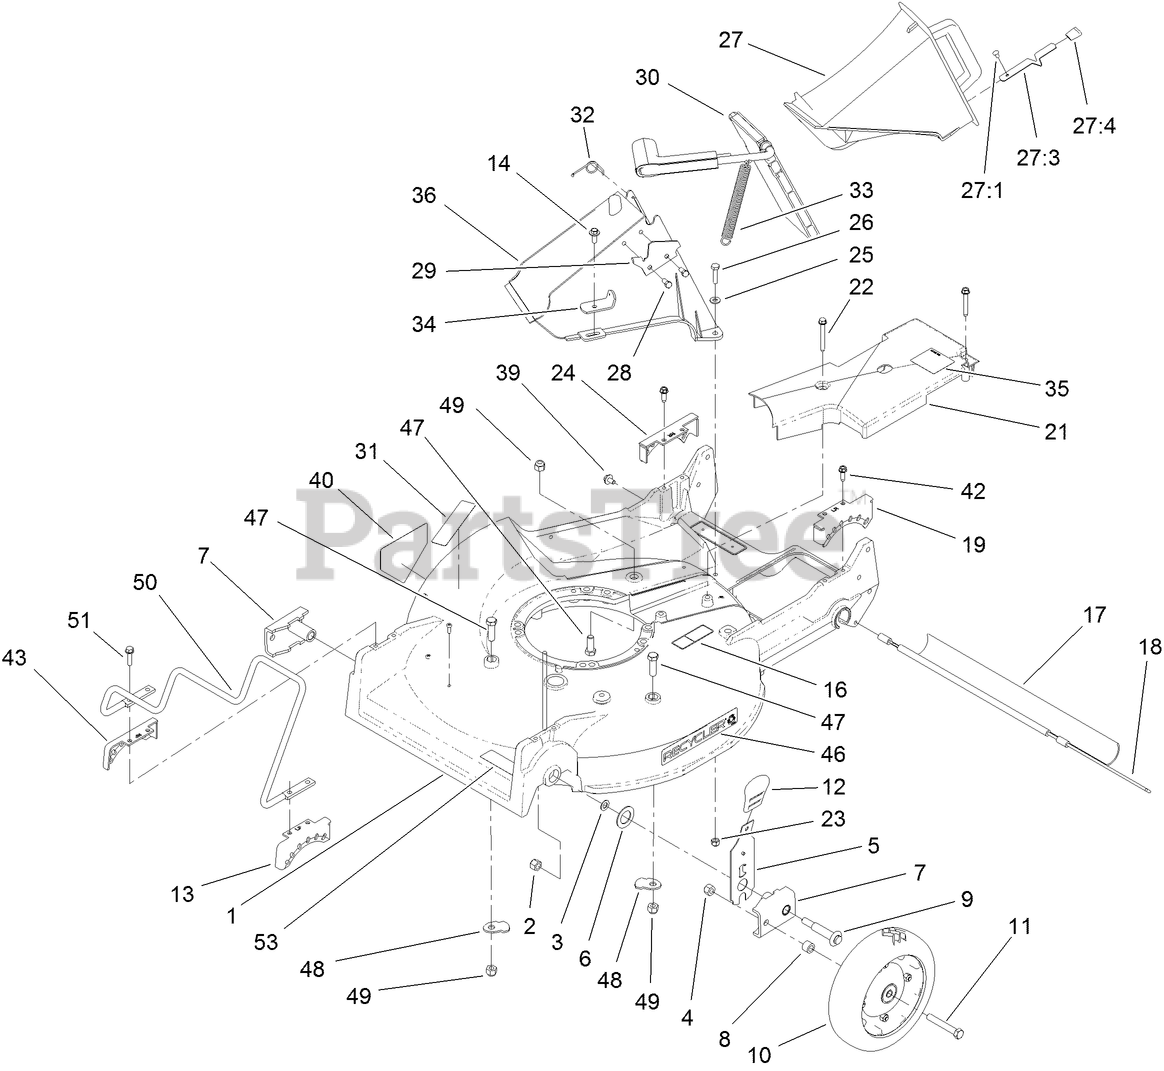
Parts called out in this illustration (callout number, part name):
1	HOUSING
2	NUT-LOCK
3	WASHER
4	NUT-LOCK, CONE
5	FRONT SPRING ARM ASM
6	WASHER-THRUST
7	ARM-PIVOT, FRONT
8	SPACER-WHEEL
9	SCREW-SHOULDER
10	WHEEL AND TIRE ASM
11	SCREW-HH
12	KNOB-HOC
13	QUADRANT-FRONT, LH
14	SCREW-HWH
16	DECAL-WARNING, BLOCK
17	SHIELD-TRAILING
18	ROD-SHIELD
19	QUADRANT-REAR, LH
21	COVER-BELT
22	SCREW-HWHTF
23	NUT-LOCK, NI
24	QUADRANT-REAR, RH
25	WASHER-FLAT
26	SCREW-HH
27	DISCHARGE PLUG ASM
27:1	RIVET-HEAD, FLAT
27:3	LATCH-PLUG, DISCHARGE
27:4	GRIP-LATCH
28	SCREW-PLASTITE
29	LATCH-PLATE
30	DISCHARGE DOOR ASM
31	DECAL-ARRESTER, SPARK
32	RETAINER-DOOR
33	SPRING-DOOR
34	BRACKET-SPRING
35	DECAL-GREASE
36	TUNNEL-DISCHARGE
39	SCREW AND WASHER ASM
40	DECAL-DANGER
42	SCREW-HWHTF
43	QUADRANT-FRONT, RH
47	SCREW-HH
48	SHIELD-RETAINER
49	NUT-LOCK, NI
50	GUARD-ENGINE
51	SCREW-HWHTF
53	DECAL-BLADE
